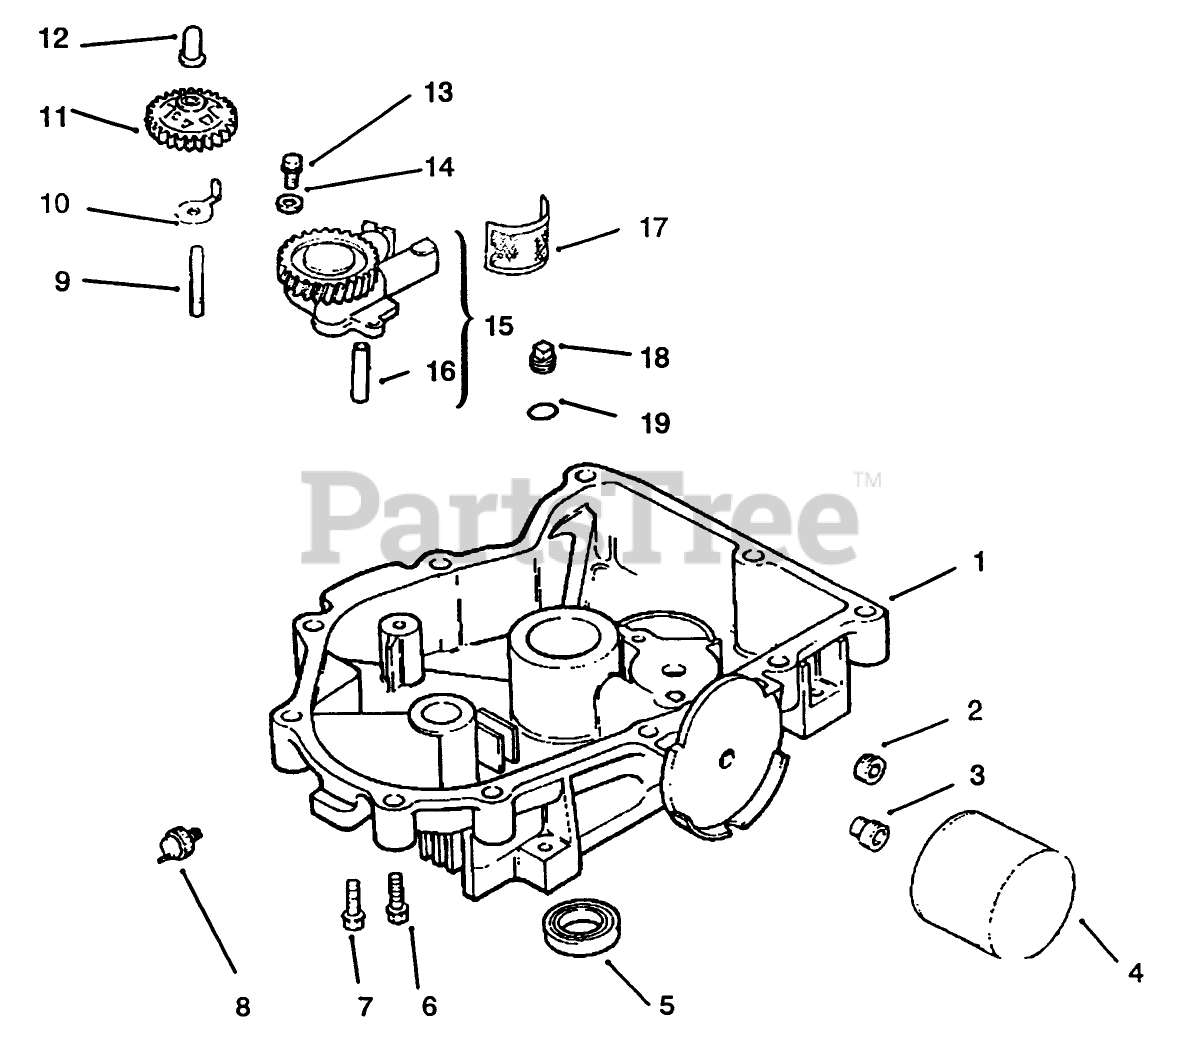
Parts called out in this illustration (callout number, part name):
1	Oil Pan (Only On: 72103)
2	Plug-HS 3/8 NPTF (Only On: 72103, 72083)
3	Nipple-Oil Filter
4	Filter-Oil
5	Seal-Oil
6	Screw M8x1.25x45 (Only On: 72103, 72083)
8	Switch-Oil Pressure
9	Shaft-Govenor Gear
10	Tab-Locking
11	Governor Gear ASM (Only On: 72103)
12	Pin-Governor
15	Oil Pump ASM INCL 16 (Only On: 72103)
16	Tube-Oil Pickup (Only On: 72103, 72083)
17	Screen-Oil Pickup (Only On: 72042, 72063, 72062, 72043)
